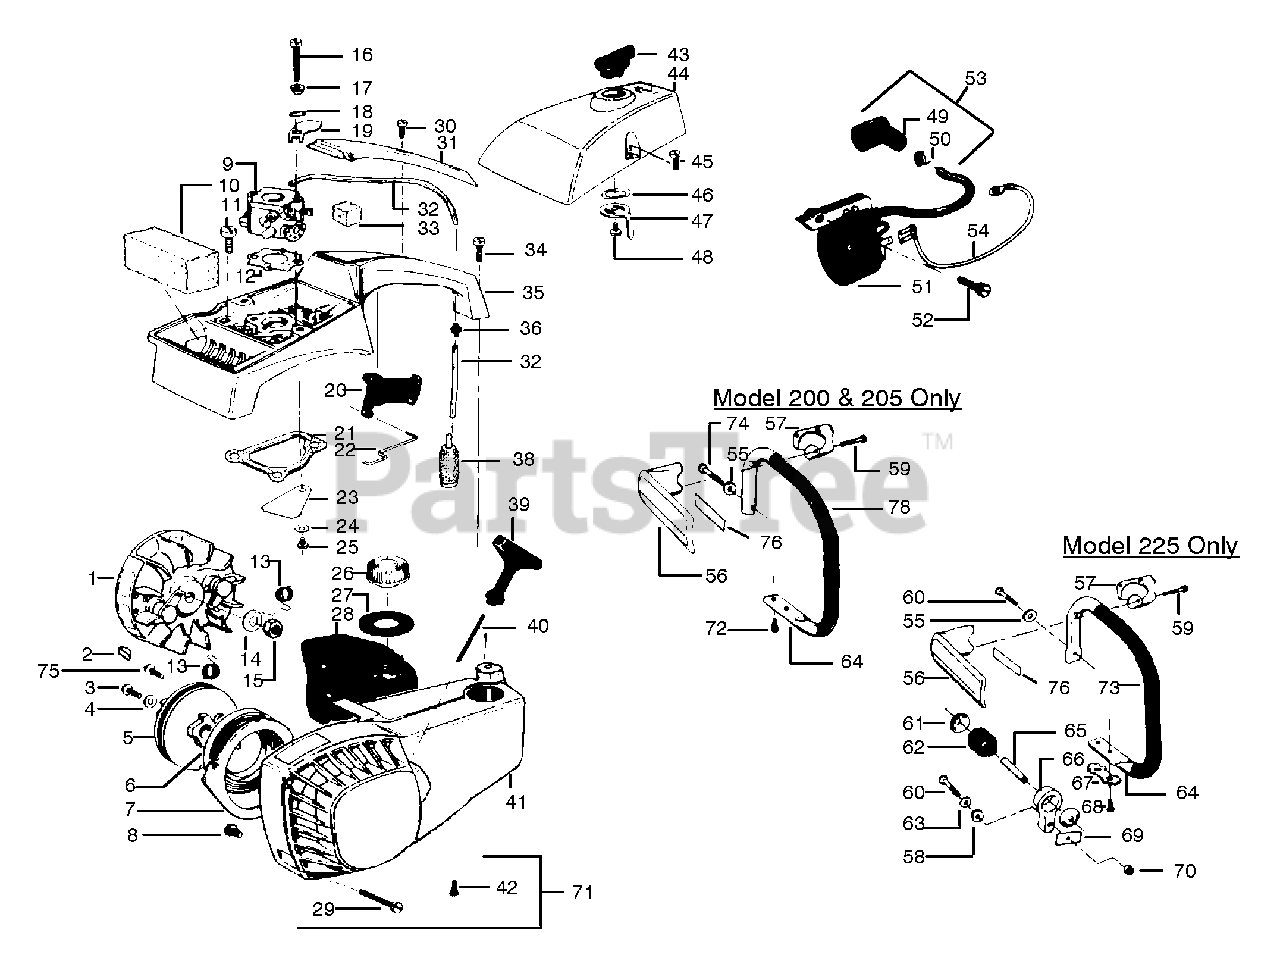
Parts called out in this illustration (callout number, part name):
1	Flywheel Ass'y.
2	Flywheel Key
3	Screw
5	Starter Pulley
6	Starter Spring
7	Air Baffle
8	Screw
9	Carburetor
10	Air Filter
12	Carburetor Gasket
13	Starter Dog Spring
14	Flywheel Washer
18	Wave Washer
19	Choke Shutter
20	Throttle Trigger
21	Gasket
22	Throttle Wire
23	Reed Valve
26	Fuel Cap Ass'y.
28	Fuel Tank Ass'y.
29	Screw
31	Handle Cover
32	Fuel Line
33	Throttle Wire Boot
35	Handle & Carb. Hsg.
36	Fuel Line Fitting
38	Fuel Pick Up Ass'y.
39	Starter Handle
40	Rope Kit
41	Fan Hsg. Kit
43	Choke Knob
44	Carb. Cover
46	Wave Washer
47	Choke Lever
49	Spark Plug Boot
50	Spark Plug Connector
51	Ignition Module Kit
53	Spark Plug Lead
54	Switch Lead
56	Handguard
57	Handguard Cap
61	Isolator Cup
62	Isolator
63	Lockwasher
64	Handlebar
66	Bracket Isolator
67	Screw Retainer
69	Cork Pad
70	Lock Nut
71	Fan Housing Screws Kit
75	Rope Retaining Screw
76	Handguard Decal
